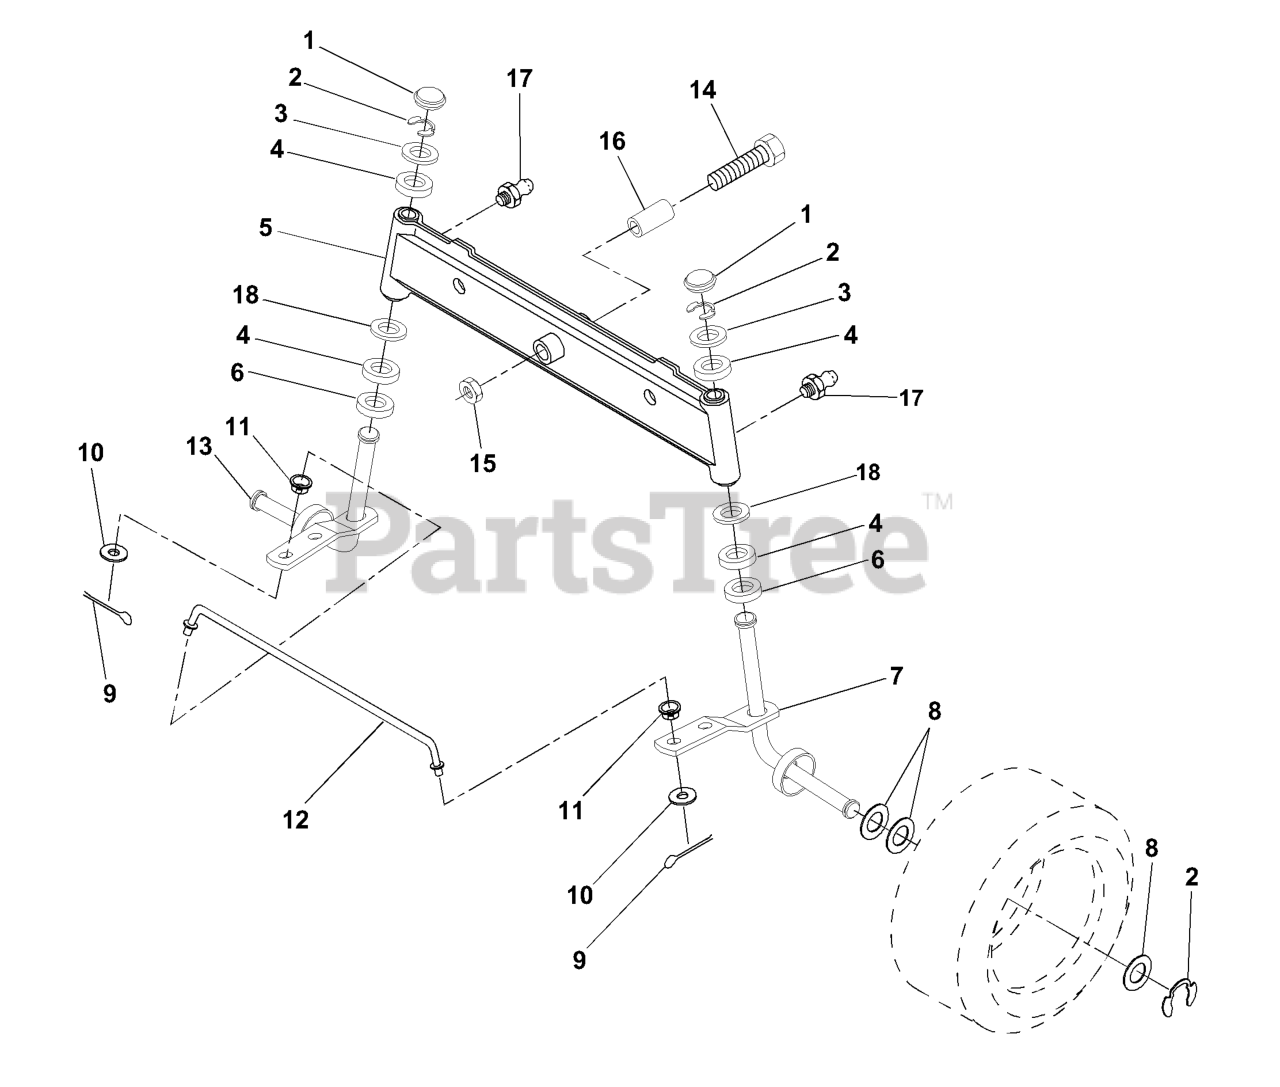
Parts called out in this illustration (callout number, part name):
1	CAP.SPINDLE.BLACK
4	BRNG T
6	THRUST WASHER
7	SPINDLE ASSY RH NLA
9	COTTER PIN
10	WASHER
11	BUSHING.DRAGLINK (2 2)
12	TIE ROD
13	SPINDLE ASSY LH
14	Bolt Hex 5/1-11 x 3-1/2
15	NUT-LOC,FLANGE LT
16	BEARING
17	ZERK M
